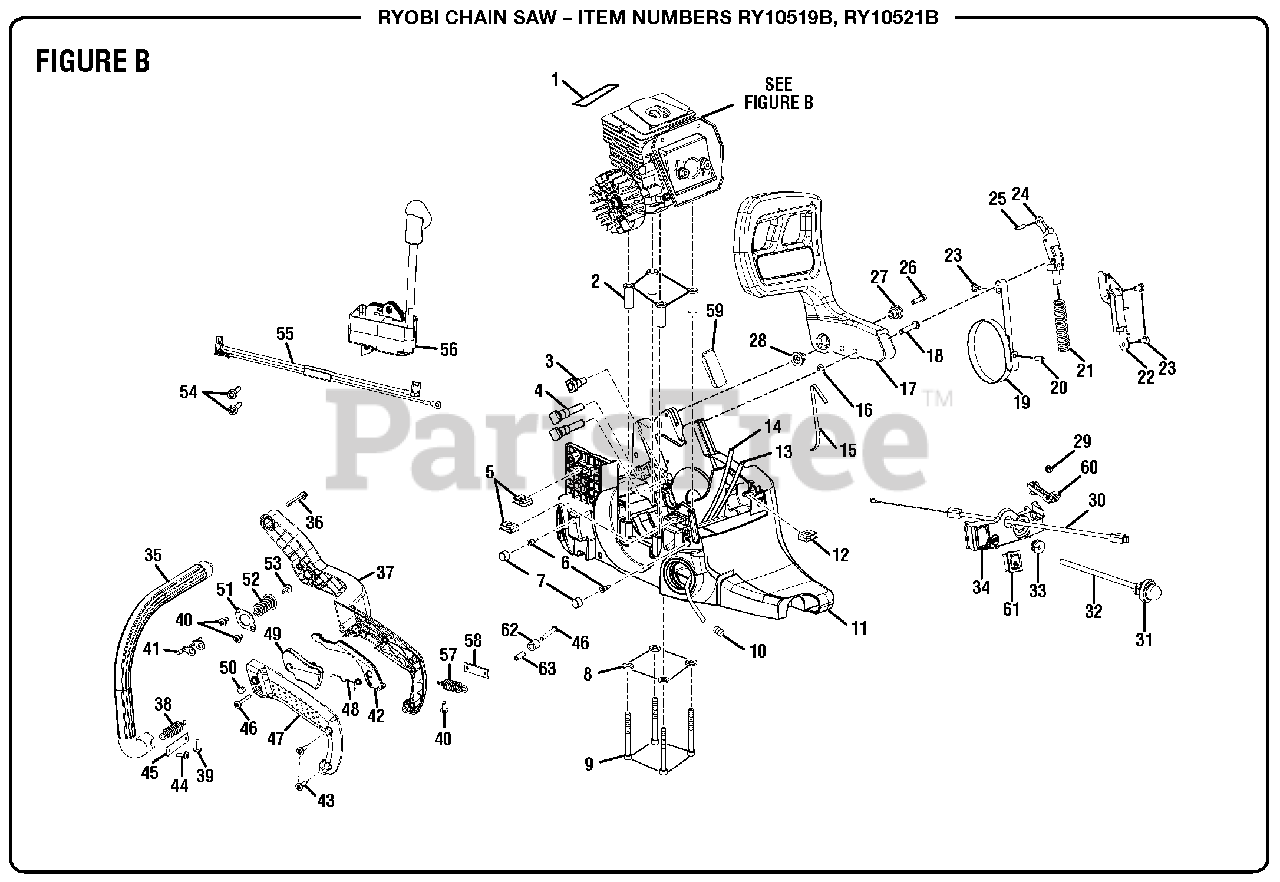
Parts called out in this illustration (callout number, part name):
1	Heat Reflector Tape
2	Spacer Insert
3	Oil Outlet Grommet
4	Guide Bar Bolt
5	Speed Nut ("U"-type)
6	Duck Bill Valve
9	Screw (10-24 x 2 in.)
10	Hose Clamp
12	Speed Nut ("U"-type)
13	Inlet Tubing (166 mm)
14	Return Tubing (220 mm)
16	Retaining Ring
17	Hand Guard Assembly
18	Hand Guard Actuating Pin
19	Brake Band
20	Spring Pin
21	Spring
22	Chain Brake Cover
23	Screw (8-16 x 5/16 in.)
24	Chain Brake Link Assembly
25	Spring Pin (Small)
26	Screw (8-32 x 5/8 in.)
27	Pivot (Right Hand)
28	Pivot (Left Hand)
30	Throttle Cable
31	Primer Bulb
32	Rubber Tubing (64 mm)
33	Split Grommet
34	Control Panel
35	Front Handle
36	Screw (12-14 x 1-1/2 in.)
37	Rear Handle
39	Screw (10-14 x 5/8 in., T.F.)
40	Screw (10-14 x 1/2 in., T.F.)
41	Limiter (Upper Isolator Spring)
42	Trigger Release
43	Screw (10-14 x 3/4 in., T.F.)
44	Screw (10-14 x 5/8 in., T.F.)
45	Spring Retainer
46	Screw (10-14 x 1-3/8 in.)
47	Handle Cover
48	Torsion Spring
51	Isolator Plate
52	Isolator Spring
53	Screw (10-24 x 5/8 in., T.F.)
54	Screw (8-32 x 3/4 in., T.F.)
55	Ignition Switch Assembly
56	Ignition Kit
58	Spring Retainer
60	Choke Lever
61	Stop Switch
62	Rubber Bumper
63	Spacer (Spring Screw)
